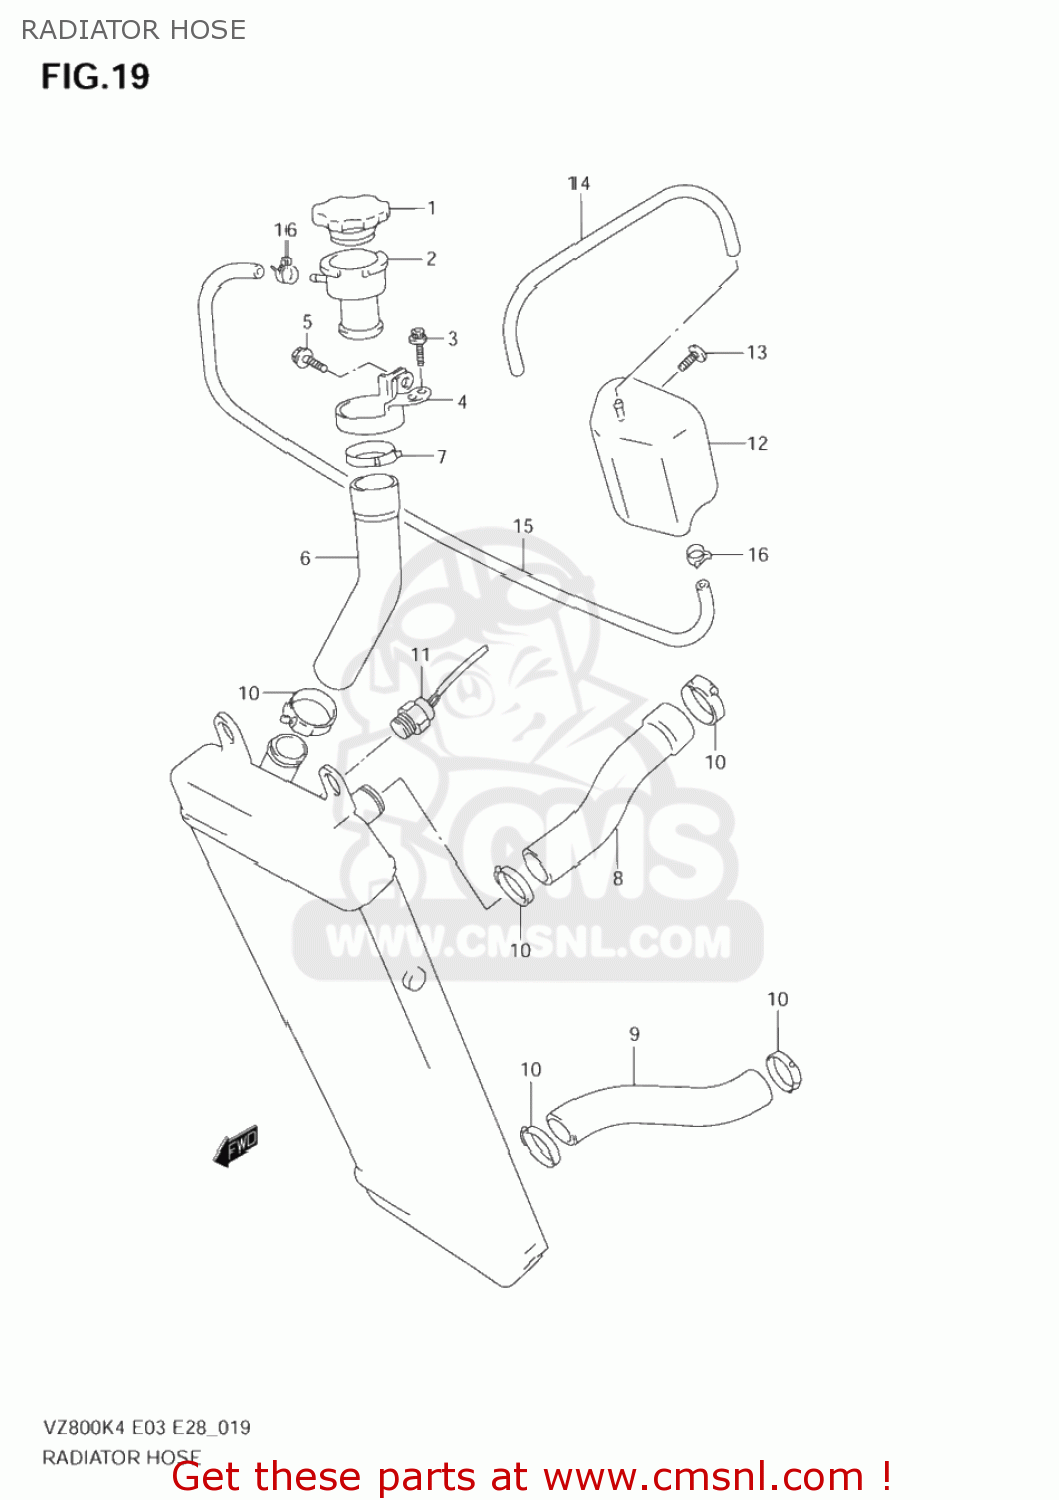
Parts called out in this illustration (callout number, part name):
1	CAP,RADIATOR
2	CONDUCTION,RADIATOR
3	BOLT MAGNETO S
4	BRACKET,CONDUCTION
5	BOLT
6	HOSE,CONDUCTION
7	CLAMP
8	HOSE,RADIATOR INLET
9	HOSE,RADIATOR OUTLET
10	CLAMP
11	SWITCH,RADIATOR FAN
12	TANK,RESERVOIR
13	SCREW 6X12
14	HOSE,RESERVOIR TANK OUTLET
15	HOSE,RESERVOIR TANK INLET
16	CLIP
